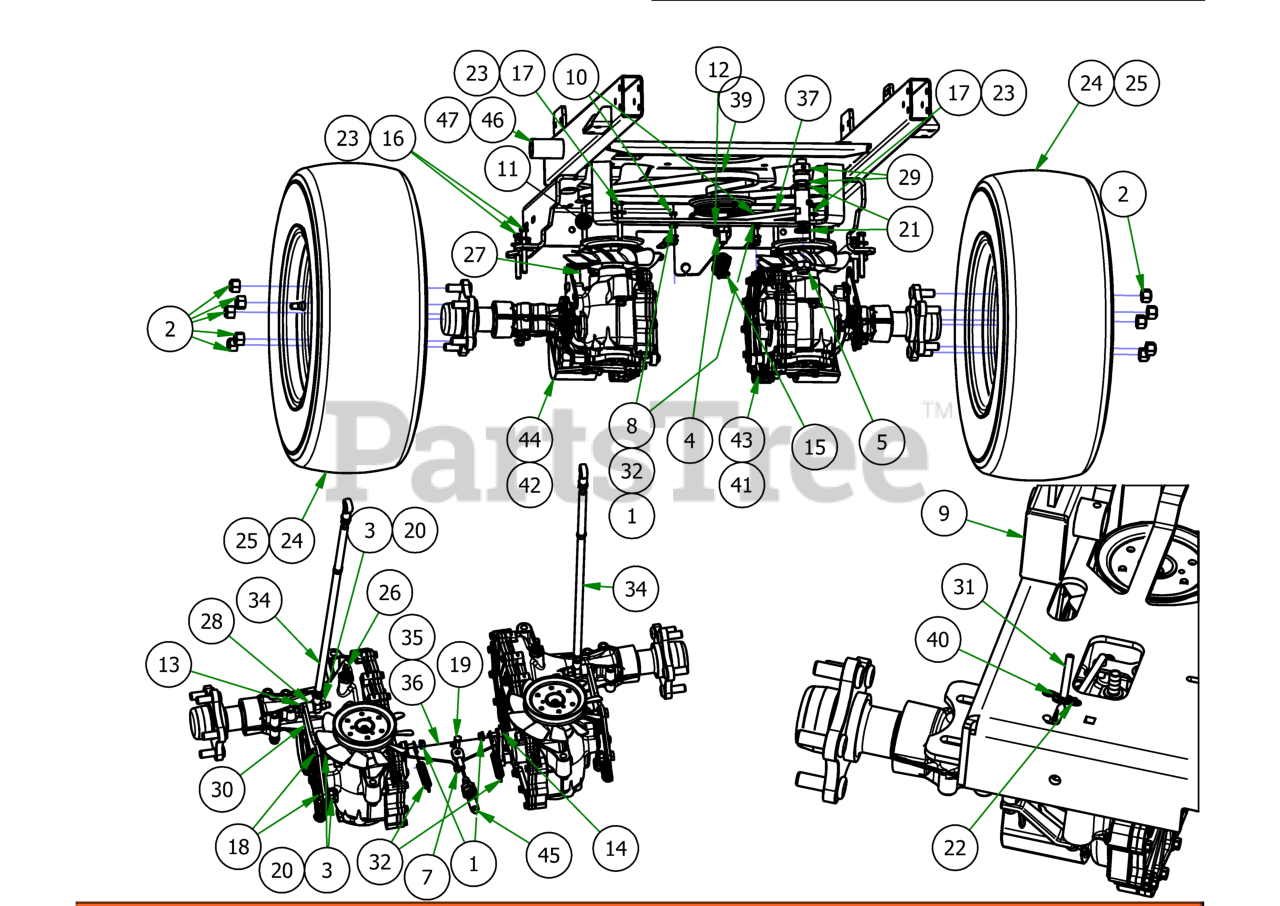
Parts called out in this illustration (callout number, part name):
1	1/4-20 Nylon Insert Flange Nut
2	Acorn Lug Nut
3	3/8-16 HEX NUT ZINC
4	1/2-13 Hex Nuts Zinc
5	5/8-11 NYLON INSERT LOCKNUT ZINC (NOT ON 36)
6	5/16-18 Nylon Flange Nut
7	1/4-20 NYLON INSERT LOCKNUT ZINC
8	1/4-20 HEX SERRATED FLANGE NUT HARD/ZINC
9	1 1/2 x 3 Frame Plug
10	1/4-20 X 2 HEX CAP SCREW (GR.5) ZINC
11	5/16x6 Carriage Bolt-Grade 5
12	All Thread
13	3/8-16 X 2 HEX CAP SCREW (GR.5) ZINC
14	1/4-20 X 1 HEX CAP SCREW (GR.5) ZINC
15	1/2-13 NYLON INSERT JAM LOCKNUT ZINC
16	5/16-18 X 3 HEX CAP SCREW (GR.5) ZINC
17	5/16-18 X 2-1/2 HEX CAP SCREW (GR.5) ZINC
18	3/8-16 X 1 GR 5 Hex Bolts Zinc
19	1/4-20 X 3/4 HEX CAP SCREW (GR.5) ZINC
20	3/8 SPLIT LOCKWASHER ZINC
21	.630 ID Plastic Washer (NOT ON 36)
22	1/4 USS FLAT WASHER (3/4 OD) ZINC
23	5/16 USS FLAT WASHER (7/8 OD) ZINC
24	23x9-12 Reaper Turf Tire & Wheel Assembly
25	21/7x10 Reaper Tire-36 Revolt
26	45 degree fitting
27	2017 Transaxle Spacer
28	ACS Spacer 3/4x3/8x1/2
29	5/8" x 1/" Collar W/One Set Screw (NOT ON 36)
30	Stand On Control Arm Plate
31	2019 Stand On Neutral Rod
32	Brake Spring
33	Deck Idler Spring
34	2019 Revolt Push Rod Assembly
35	2020 36 Brake Bracket
36	Brake Bracket
37	2019 Stand On Idler Assembly (NOT ON 36)
39	2019 Stand On Pump Belt (Timken# 47-2827)
41	Left ZT Transaxle
42	Right ZT Transaxle
43	Left 3400 IZT
44	Right 3400 IZT
45	Brake Cable
46	2019 Stand On Frame Weldment
47	2020 36 Stand On Frame Weldment
